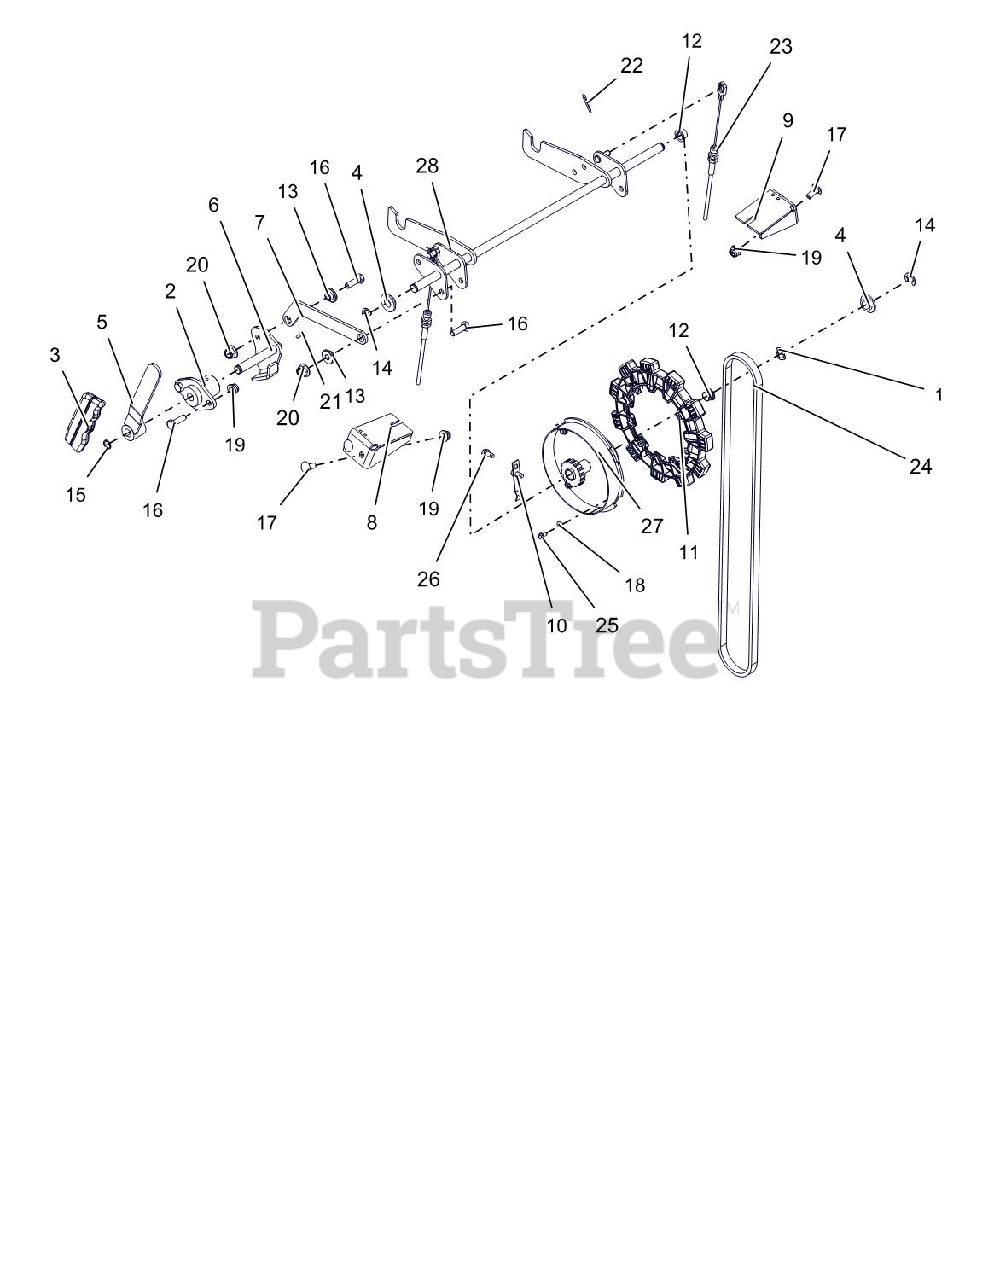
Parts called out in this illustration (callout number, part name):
1	WAVE WASHER .531X.781X.125FH
2	BUSHING, FLANGED
3	GRIP, PARKING BRAKE (YELLOW)
4	BSHG-FLG .515X.750X.310X1.120
5	WMT, PARKING BRAKE HANDLE
6	WMT, PARKING BRAKE ACTUATING
7	LINK, BRAKE INTERLOCK
8	BRKT, BRAKE CABLE MTG
9	BRKT, LH CABLE MTG
10	ARM, HOC DETENT
11	WHEEL, HOC
12	BUSHING, POLYLINER-.50 SPLIT
13	BSHG-FLG .32X.500X.344X.880
14	RG-RTNG-EXT .500X.042 (E)
15	RG-RTNG-EXT .500X.050 (SNAP)
16	@BLT-HEX .31-18X1.00 GR5 YWZC
17	@BLT-RDHDSQNK .31-18X.75 G5YZ
18	@WSHR-FL-STL.219X.50X.049 YWZC
19	@NUT-LK-NYL-FLG .31-18 YWZC
20	@NUT-LK-NYL-FLG .38-16 YWZC
21	KEY-WDRF .13X.63 HRD#5
22	PIN-HAIR INT .08X.18X1.18 YWZC
23	CABLE, PROSTANCE P.BRAKE
24	BELT, TIMING LONG
25	SCR-TAP 10-24X.375 PRE-COAT 80
26	SCR-TAP .25-20X.50 HWH TR YWZ
27	KIT, 48-60" HOC WLDMT W/DECAL
28	WLDMT, PS BRAKE INTERLOCK
